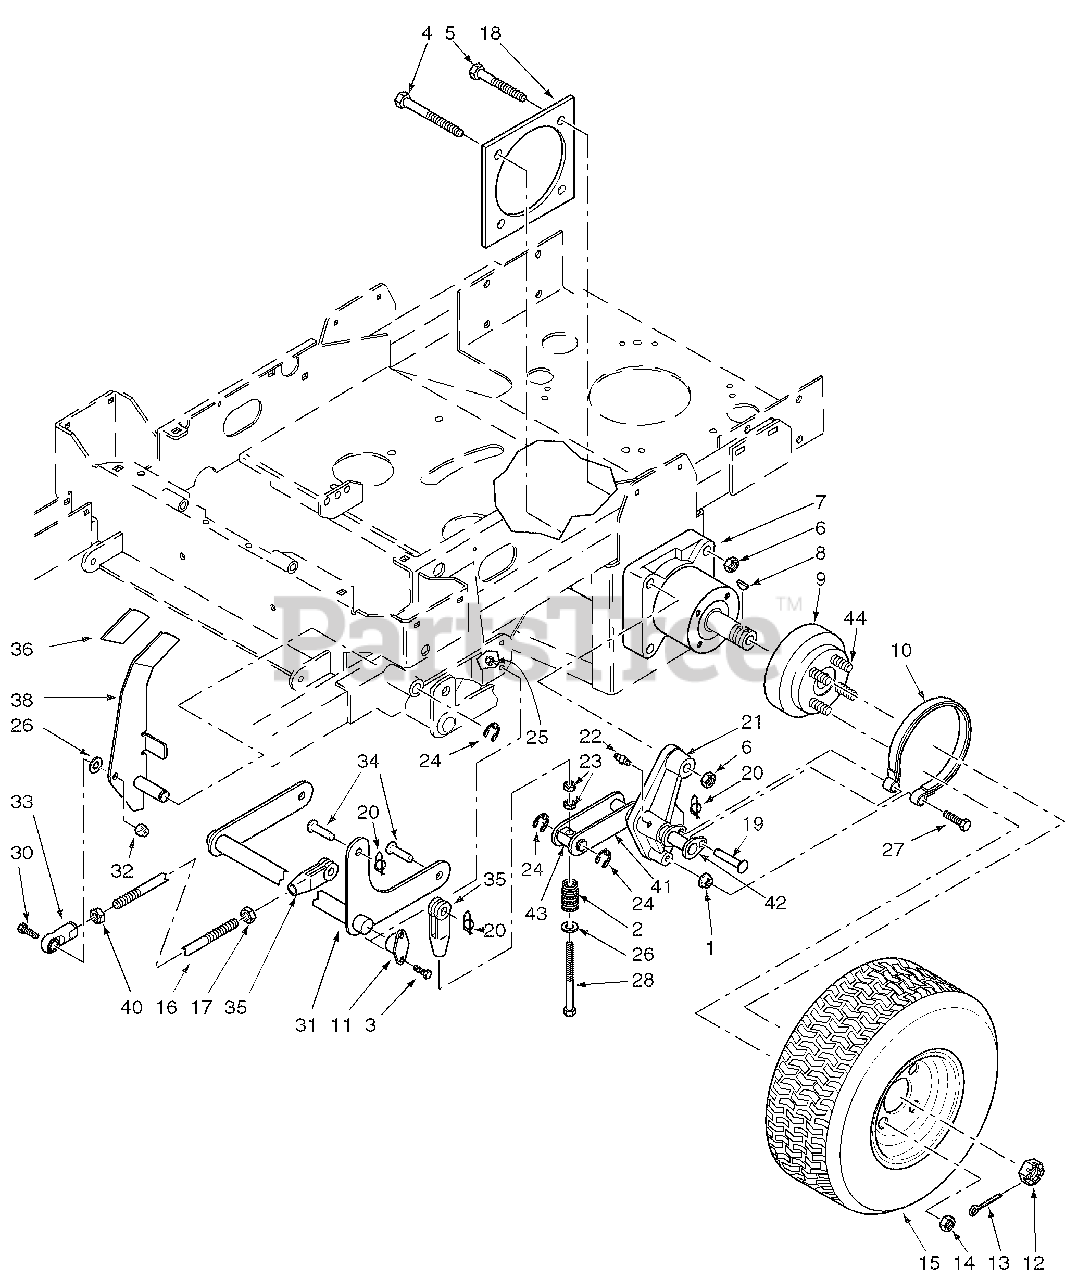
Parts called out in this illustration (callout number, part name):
1	Nut, Serr. Flange 1/2-13
2	Spring
3	Bolt, Hex Head 5/16-18 x 3/4"
4	Bolt, Hex Head 1/2-13 x 3-3/4"
5	Bolt, Hex Head 1/2-13 x 2-1/2"
6	Nut, 1/2-13 Center Lock
7	Wheel Motor, Hydro-Gear
8	Key, Woodruff 5/16 x 1"
9	Wheel Hub Assembly
10	Brake Band Assembly
11	Bushing, Self Align
12	Nut, Hex Castle 1.0-20 UNEF
13	Cotter Pin, 9/64 x 1-1/2"
14	Lug Nut, 1/2-20
15	Wheel Assembly 24 x 12 - 12
15	Rim w/Stem
15	Tire 24 x 12 - 12
16	Brake Rod Stud, 3/8-24 x 8-1/8"
17	Nut, 3/8-24 UNF
18	Plate Weldment, Motor Backing
19	Clevis Pin, 3/8 x 1.93"
20	Pin, Rue Cotter 3/8" Dia.
21	Brake Linkage LH
22	Grease Fitting, 1/4-28
23	Nut, 3/8-24 UNF
24	Retaining Ring, .625 Ext.
25	Nut, Elastic Stop 5/16-18
26	Flatwasher, 3/8-.391 x .938 x .105
27	Bolt, Hex Head 1/2-13 x 2-1/2" Grade 8
28	Bolt, Hex Head 3/8-24 x 3-3/4"
29	Cotter Pin, 3/32 x 3/4"
30	Bolt, Hex Head 3/8-16 x 1-1/2"
31	Brake Shaft
32	Nut, Elastic Stop 3/8-16
33	Rod End, 3/8-24 LH Thread
34	Clevis Pin, 3/8 x 1.06
35	Clevis, 3/8-24
36	Grip, Brake Lever
37	Nut, Serr. Flange 3/8-16
38	Brake Lever
39	Bolt, Hex Head 3/8-16 x 2-3/4"
40	Nut, 3/8-24 UNF-2B LH Thread
41	Lever, Brake
42	Shaft Weldment, Pivot
43	Pin, Pivot
44	Bolt, Serr. Flange 1/2-20 x 4.563"
